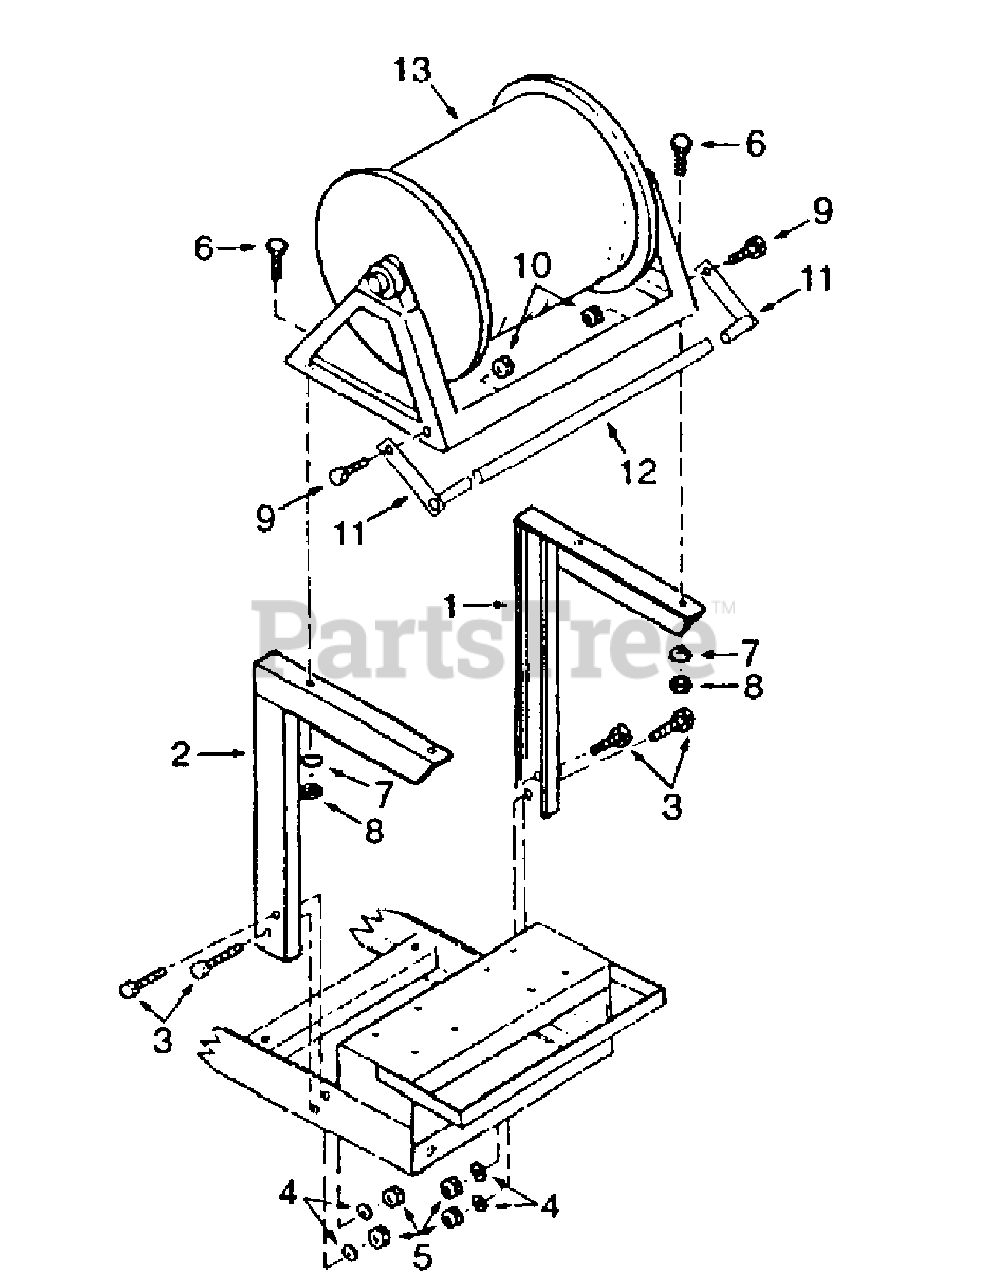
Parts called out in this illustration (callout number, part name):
1	Hose Reel Mounting Bracket
2	Reel Support, Right Hand
3	Reel Support, Left Hand
4	Cap Screw, 1/2-13 x 2 Hex Hd
5	Lock Washer, 1/2
6	Hex Nut, 1/2-13
7	Cap Screw, 3/8-16 x 1 Hex Hd
8	Lock Washer, 3/8
9	Hex Nut, 3/8-16
10	Cap Screw, 7/16-14 Hex Hd
11	Hex Nut, 7/16-14 Nylock
12	Mounting Bracket, Hose Guard
